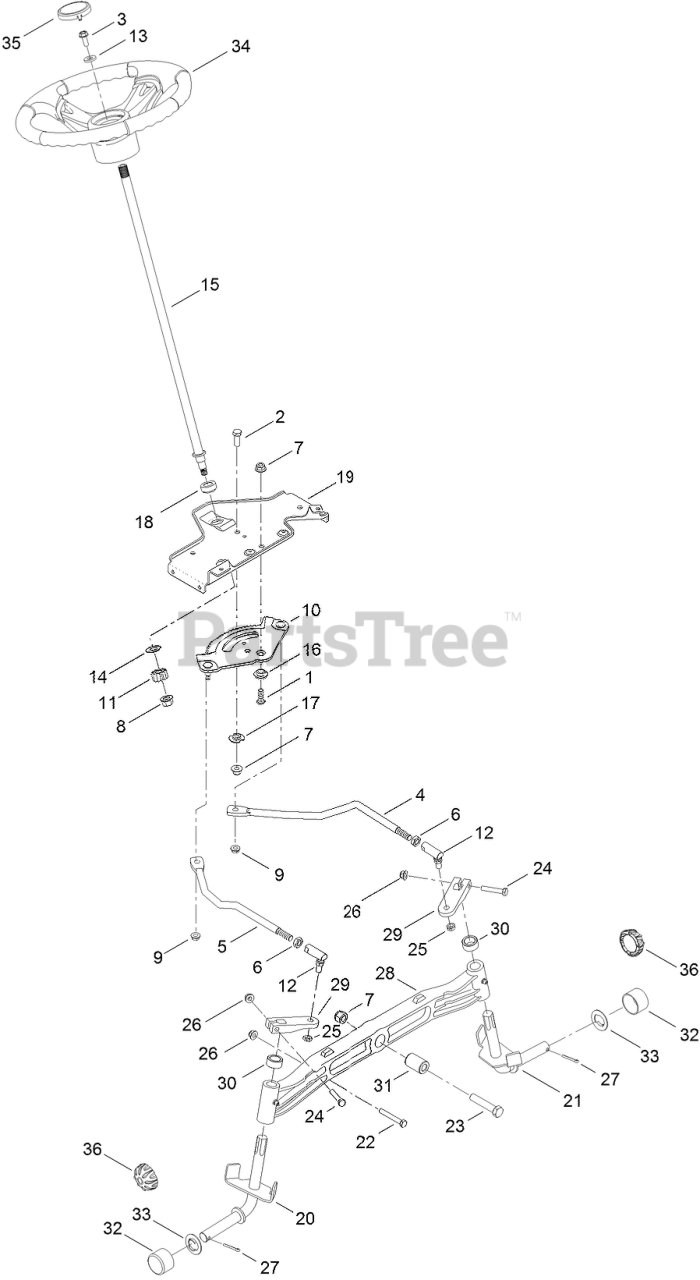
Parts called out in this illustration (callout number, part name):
1	SCREW-HH
2	SCREW-HH
3	SCREW-HH
4	LINK-DRAG, LH
5	LINK-DRAG, RH
6	NUT-JAM
7	NUT-LOCK, FLANGE
8	NUT-LOCK, FLANGE
9	NUT-LOCK, FLANGE
10	GEAR-STEERING
11	GEAR-PINION, STEERING
12	BALL JOINT ASM
13	WASHER-FLAT
14	WASHER-FLAT
15	SHAFT-STEERING
16	SPACER-SHOULDER
17	SPACER
18	BEARING-FLANGE, HEX
19	BRACKET-SUPPORT, STEERING
20	RH AXLE ASM
21	LH AXLE ASM
22	SCREW-HH
23	SCREW-HH
24	BOLT-HH
25	NUT-HEX, LOCK
26	NUT-LOCK, FLANGE
27	PIN-COTTER
28	AXLE-CAST
29	BLOCK-STEERING
30	SPACER
31	SPACER
32	CAP-HUB
33	WASHER-FLAT
34	STEERING WHEEL ASM
35	CAP-WHEEL, STEERING
36	CAP-HUB
